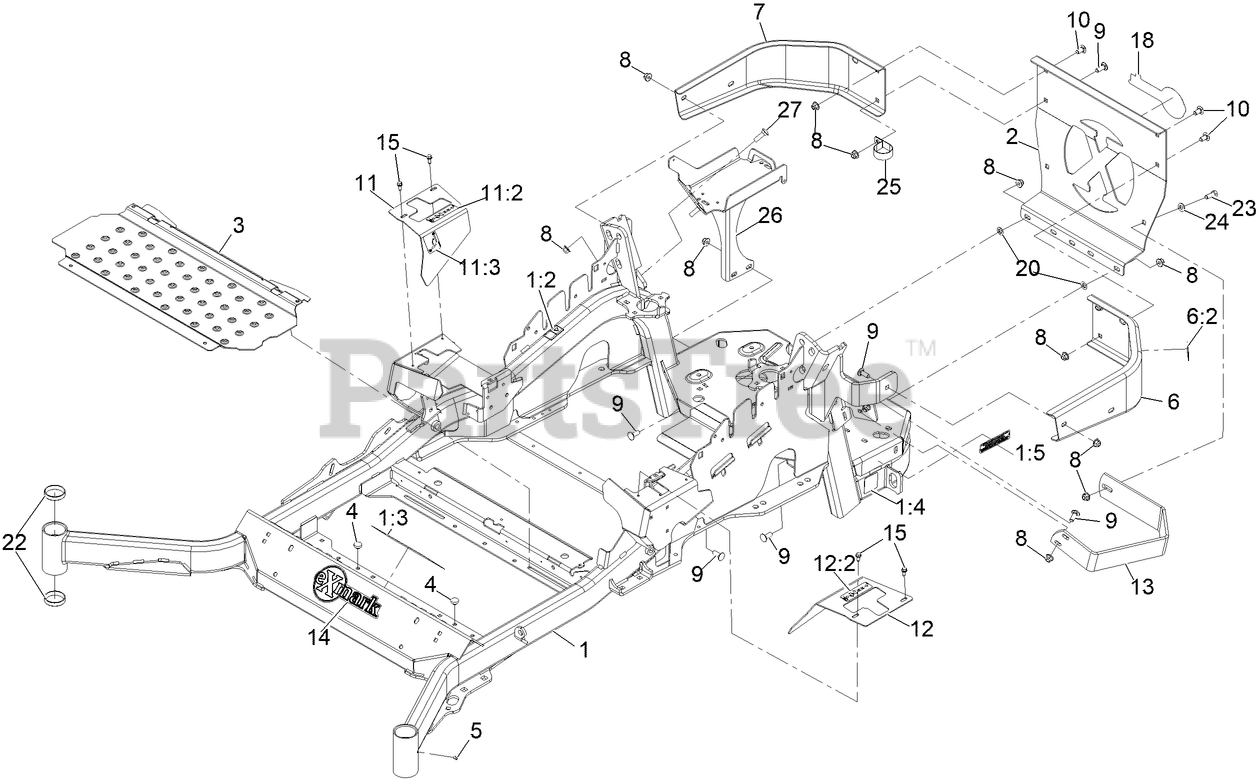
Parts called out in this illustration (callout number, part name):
1	MAINFRAME SERVICE ASM - 72
1:2	DECAL-WARNING
1:3	DECAL-DANGER
1:4	DECAL-HAZARD, PINCHED FINGER
1:5	DECAL-ARRESTOR, SPARK
2	PLATE,REAR GUARD
6	LH BUMPER ASM
6:2	DECAL-WARNING
7	BUMPER-RH
8	NUT-HF, NI
9	SCREW-CARR
10	SCREW-CARR
11	RH MOTION CONTROL COVER ASM
11:2	DECAL-CONTROL, MOTION
11:3	DECAL-PARK BRAKE, CE
12	LH MOTION CONTROL COVER ASM
12:2	DECAL-CONTROL, MOTION
13	GUARD-MUFFLER
14	DECAL-EXMARK
15	SCREW-HWH
18	DECAL, EXMARK LOGO
20	NUT-PUSH
22	CUP-BEARING
23	SCREW-HH
24	WASHER-FLAT
25	CLAMP-R
26	BATTERY MOUNT ASM
27	BOLT-CARR
